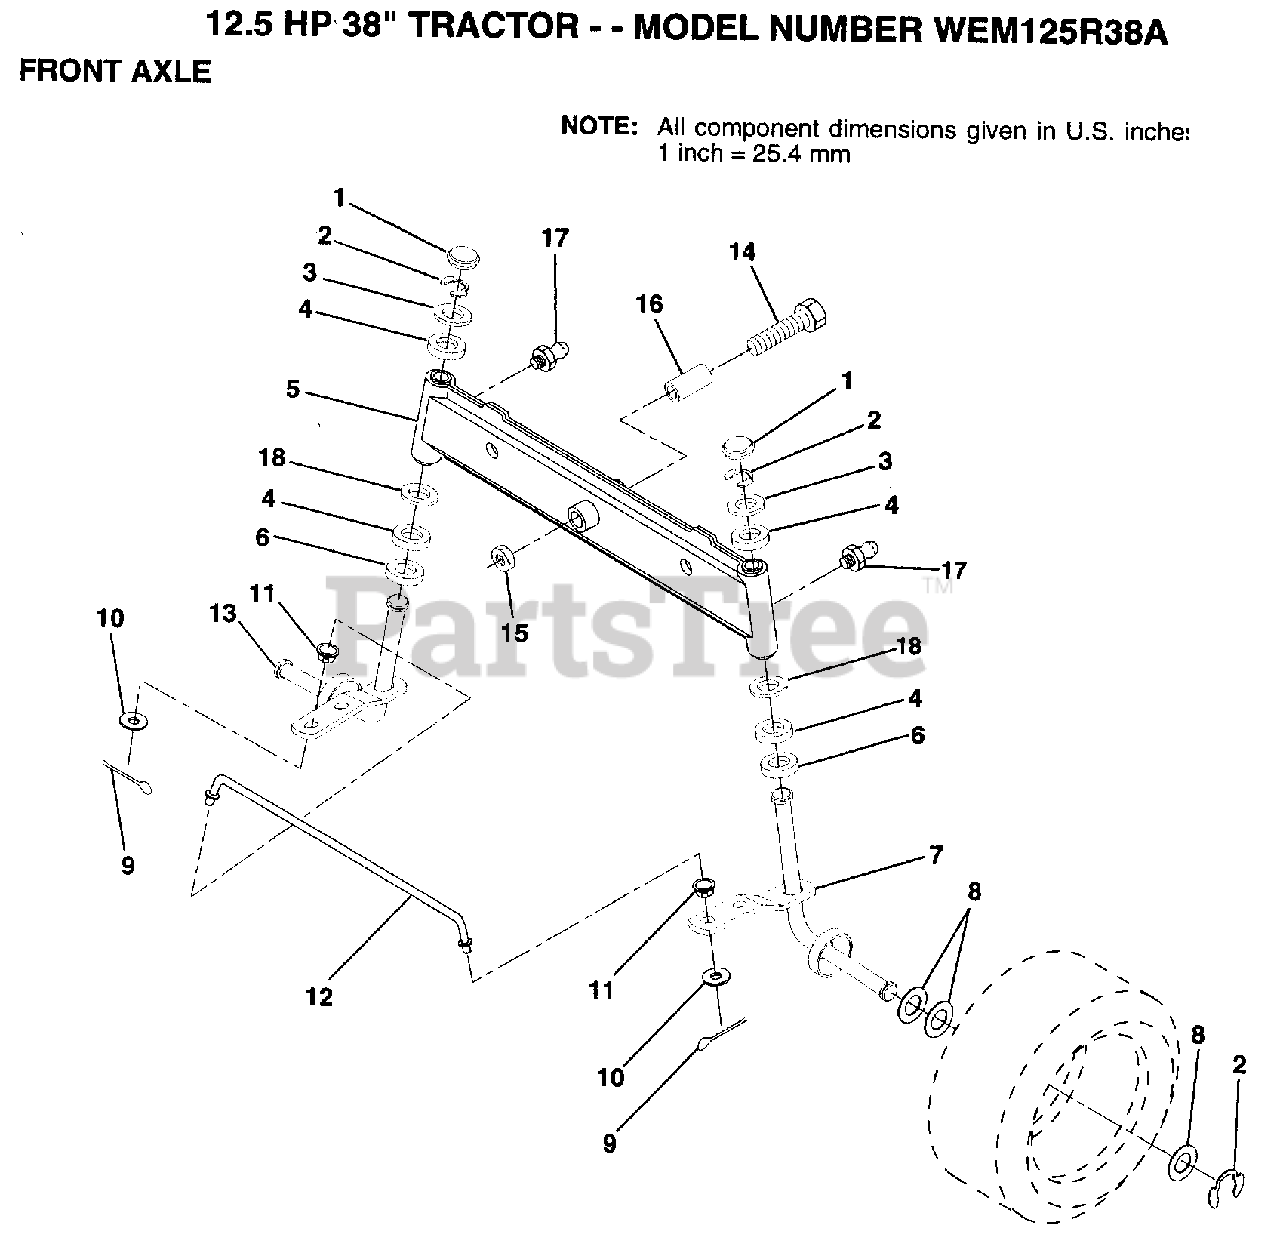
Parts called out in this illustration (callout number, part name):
1	CAP
2	RING
3	WASHER
4	COL. SRTG. BEAR.
5	AXLE ASM FRONT
6	WASHER .T
7	SPINDLE ASM RH
8	WASHER
9	COTTER PIN
10	WASHER
11	BUSHING.DRAGLINK
12	TIE ROD
13	SPINDLE ASM LH
14	BOLT HEX 5/8-11
15	"NUT-LOC,FLANGE LT"
16	BEARING
17	ZERK M
18	WASHER
